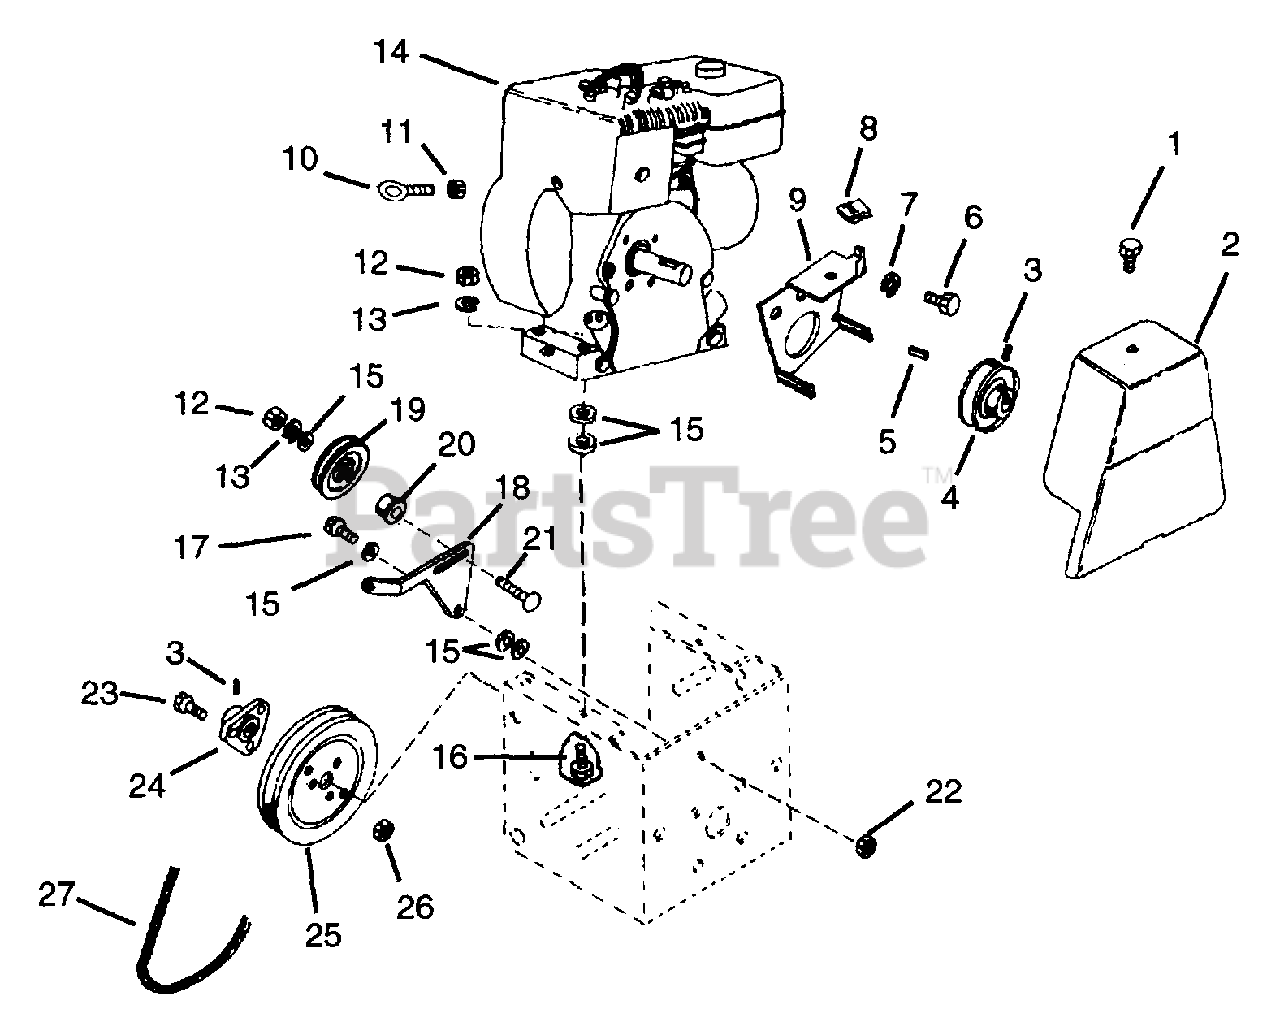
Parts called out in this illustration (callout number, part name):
1	BLT-HEX .31-18X.50 PL GR2
2	BELT COVER
3	SCR-SET .32-18X.38 SKHCUPNL OH
4	ENGINE SHEAVE
5	KEY-SQ .188X1.0X.188 SAE 8630
6	BLT-HEX .75-16X2.50 PL GR5
7	WSHR-LK .500X.151 HVY PL
8	NUT-SPEED U-TYPE .312-18
9	BELT FINGER & COVER BRACKET
10	ROD HANGER EYEBOLT
11	NUT-LK-CTR .250-20 PL
12	NUT-HEX .312-18
13	WSHR-LK .312X.097 PL HVY
14	TECUMSEH 3HP TILLER ENG.
15	WSHR-FL-STL .38X.875X.083 PL
16	BLT-HEX .31-18X1.75 PL GR2
17	BLT-HEX .31-18X1.00 PL GR 2
18	IDLER BRACKET
19	IDLER
20	SPCR, BRG .315X.50X.688X.281
21	BLT-RDHDSQNK .31-18X1.38SHT PL
22	NUT-LK .312-18 GR A PL
23	BLT-SERRDHD SL .31-18X.75 YZ
24	HUB
26	NUT-FLG. .312-18 PL
27	V-BELT, 4L-RAW EDGE
